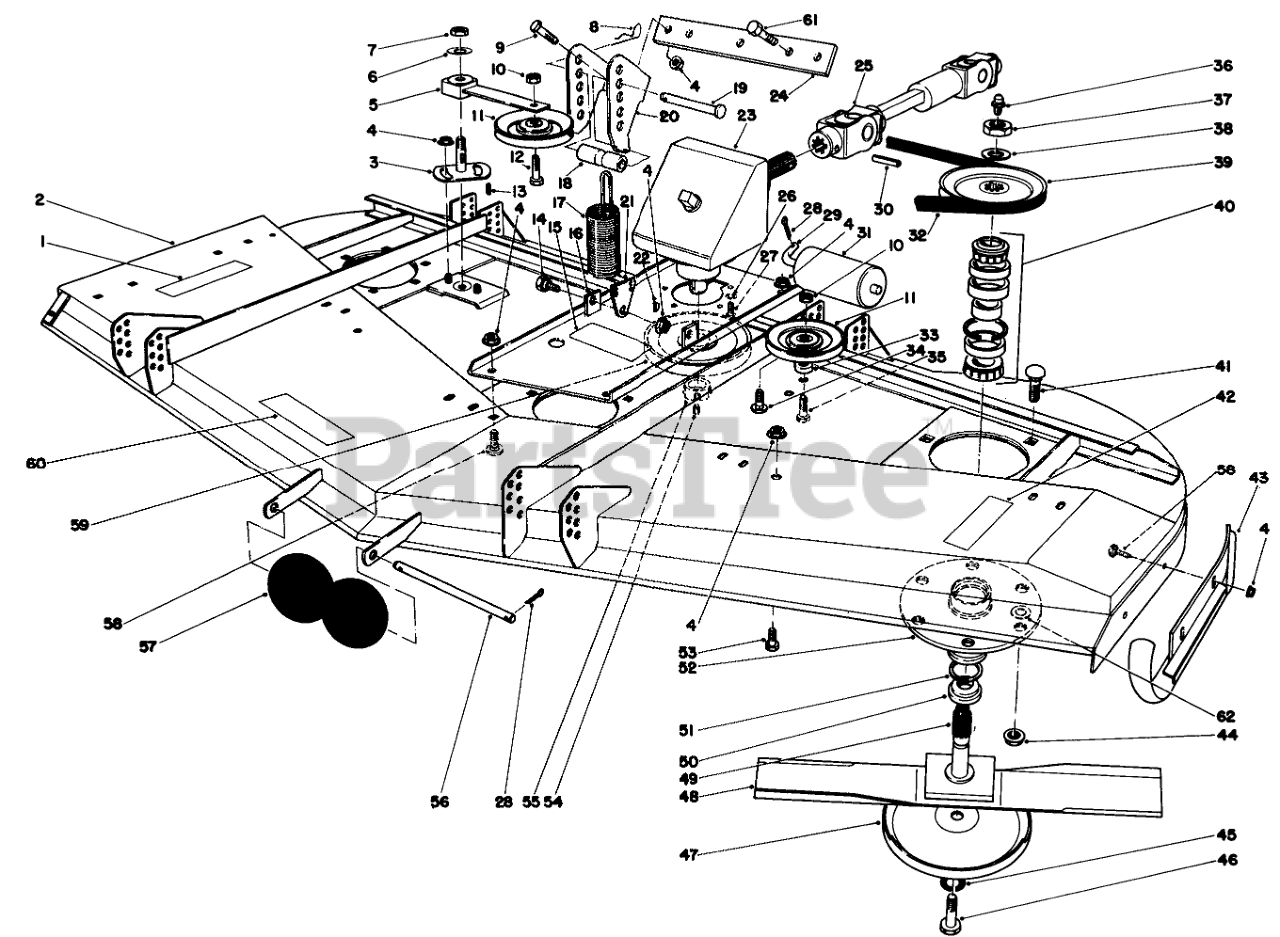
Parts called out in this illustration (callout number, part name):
1	DECAL-CAUTION, DEFLECTOR
2	Cutting Deck
3	PLATE-IDLER
4	NUT-HHF, WHIZ
5	IDLER ARM ASM
6	WASHER-FLAT
7	NUT-LOCK, NI
8	PIN-HAIR
9	SCREW-HH
10	NUT-HEX
11	Idler Pulley
12	SCREW-HH
13	KEY-SQUARE
14	BOLT-SHOULDER
15	Decal-Caution
16	GEARBOX BASE WA R
17	Spring-Extension
18	SPACER
19	PIN-CLEVIS
20	SPRING BRACKET R
21	SPRING END R
22	KEY-WOODRUFF
23	GEAR BOX ASM
24	BRKT MOUNT R
25	UNIVERSAL JOINT
26	WASHER-LOCK
27	SCREW-HSH
28	PIN-COTTER
29	SHAFT-ROLLER, REAR
30	PIN-ROLL
31	ROLLER-DECK
32	V-BELT
33	SPACER
34	SCREW-CARR
35	SCREW-HH
36	FITTING-GREASE
37	NUT-HEX
38	WASHER
39	PULLEY AND HUB ASM
40	BEARING ASM
41	SCREW-CARR
42	DECAL-CAUTION, BLADE
43	L.H. Skid
44	NUT-HF
45	WASHER-LOCK
46	SCREW-BLADE
47	Cup-Scalp
48	Blade
49	SHAFT
50	SPACER
51	SEAL-OIL
52	Housing-Spindle
53	SCREW-HH
54	SCREW-SET, HSH
55	BUSHING-LOCK, TAPER
56	SHAFT-ROLLER
57	ROLLER
58	SCREW-CARR
59	PULLEY WA BO
60	Decal-Caution
61	SCREW-HH
62	WASHER-FLAT
